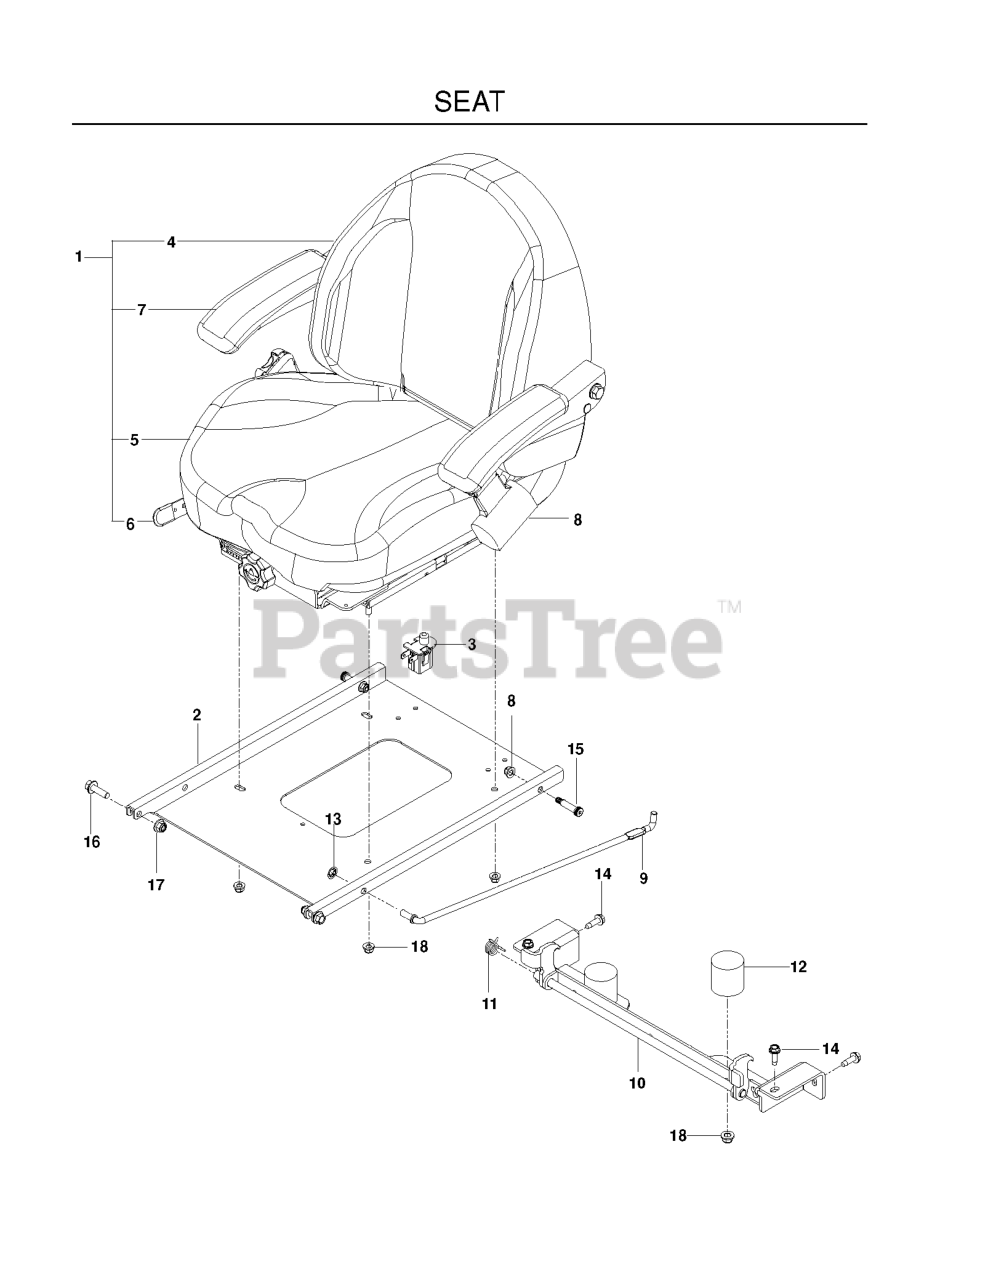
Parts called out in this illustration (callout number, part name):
1	Seat Assy
2	PAN, SEAT, BLACK
3	SEAT SWITCH
4	COVER, BACK
5	COVER KIT, CUSHION
7	ARMREST, LT
8	SEAT BELT, RETRACTABLE
10	LATCH.SEAT.BLACK
11	SPRING, TORSION
12	BUMPER, RUBBER
13	NUT 3/8 PALNUT RTNG BLK PHOS
14	RP BLT 5/16-18 X 1 THRD FORM D
15	BOLT, SHOULDER 3/8 X 1.25
16	HHFS 3/8-16 X 1.25 GD 5
17	NUT 3/8-16 HEX FLG NYLOC ZD
18	5/16-18 NYLOC FLANGE NUT
